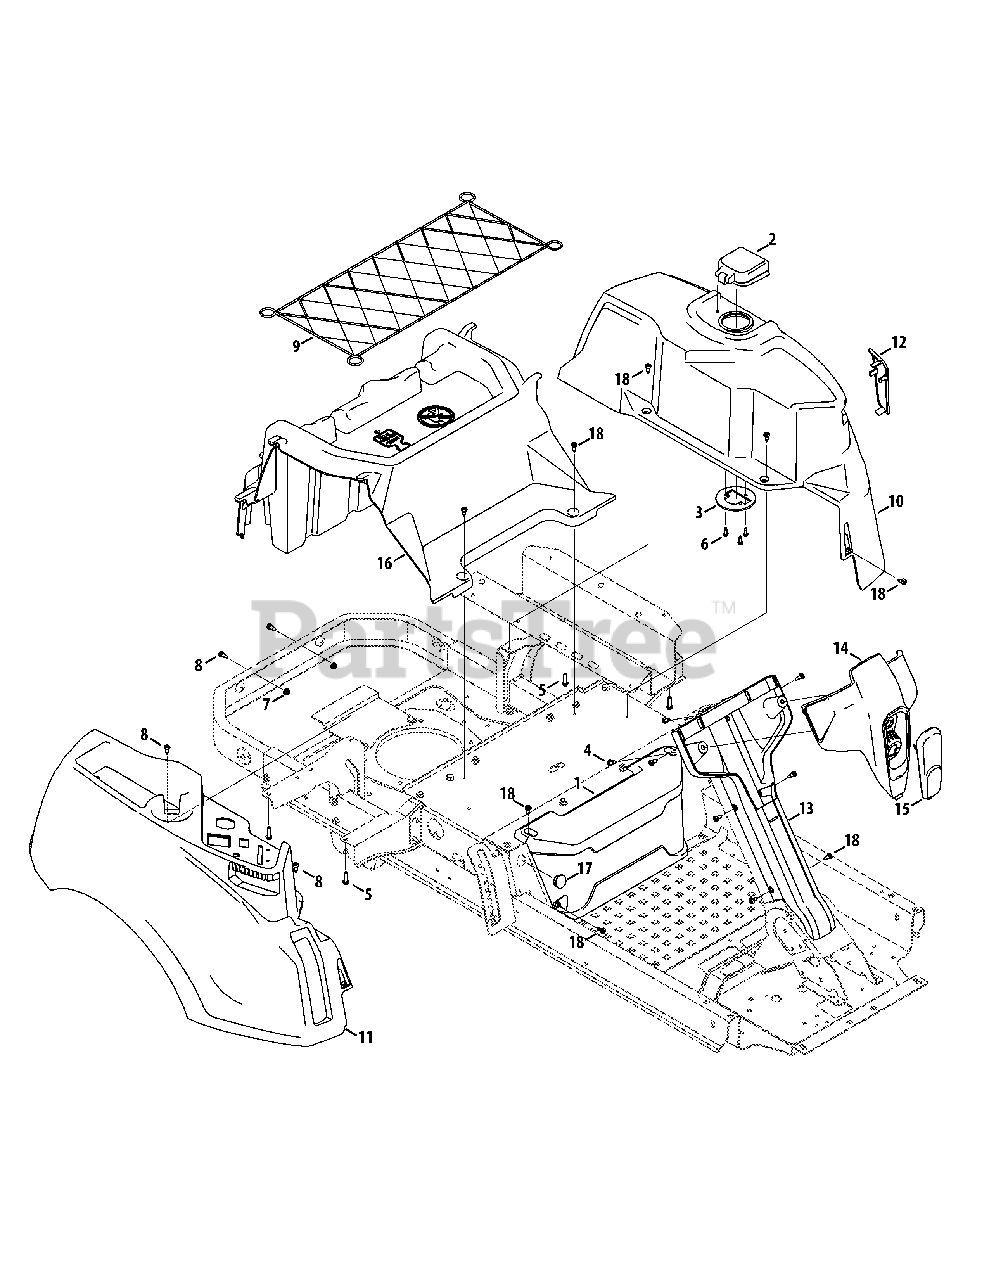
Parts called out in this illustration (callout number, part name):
1	Battery Cover, Front
2	Charge Port Plug Assembly
3	Charge Port Mounting Plate
4	Screw, 1/4-10 x .625
5	Hex Washer Screw, 5/16-14 x 1.00
6	Screw, #12-16 x .625
7	Flange Lock Nut, 1/4-20
8	Shoulder Screw, .368 x .115, M6-1
9	Cargo Retainer
10	Console, LH
11	Console, RH
13	Column Cover
14	Control Module Cover
16	Battery Cover
17	Plastic Plug
18	Shoulder Screw, 1/4-20
